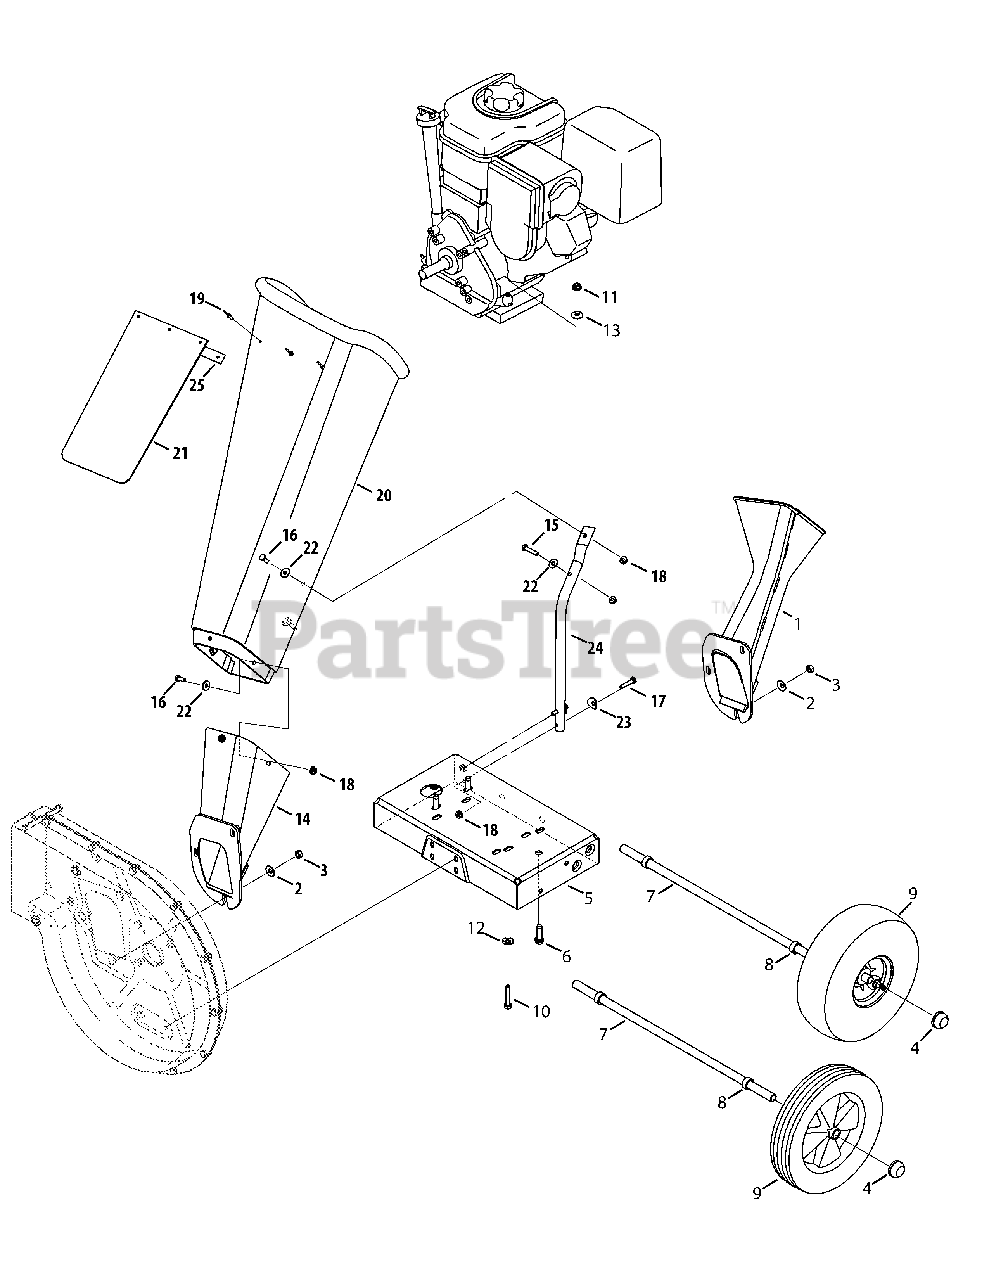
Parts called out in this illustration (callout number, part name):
1	Chipper Shredder Chute
2	Bell Washer.340 ID x.872 OD
3	Hex Nut 5/16-18
4	Push Cap
6	Screw, 3/8-16 x 1.250
7	Axle Assembly
8	Spacer
9	Wheel Comp., 10.0 x 4.0 Gray
10	Hex Cap Screw 5/16-18 x 1.50
11	Hex Lock Nut 5/16-18
12	Bell Washer 5/16 x 1.0
13	Bell Washer.340 ID x.872 OD
14	Chipper Chute Assembly
15	Hex Cap Screw 1/4-20 x 1.25
16	Hex Cap Screw 1/4 -20 x.620
17	Hex Cap Screw, 1/4-20 x 1.250
18	Hex Lock Nut 1/4-20
19	Pop Rivet
20	Chipper Shredder Chute
21	Chute Flap
22	Flat Washer.28 ID x.74 OD
23	Washer,.320 ID x.93 OD
24	Support Brace
25	Chute Flap Strip
